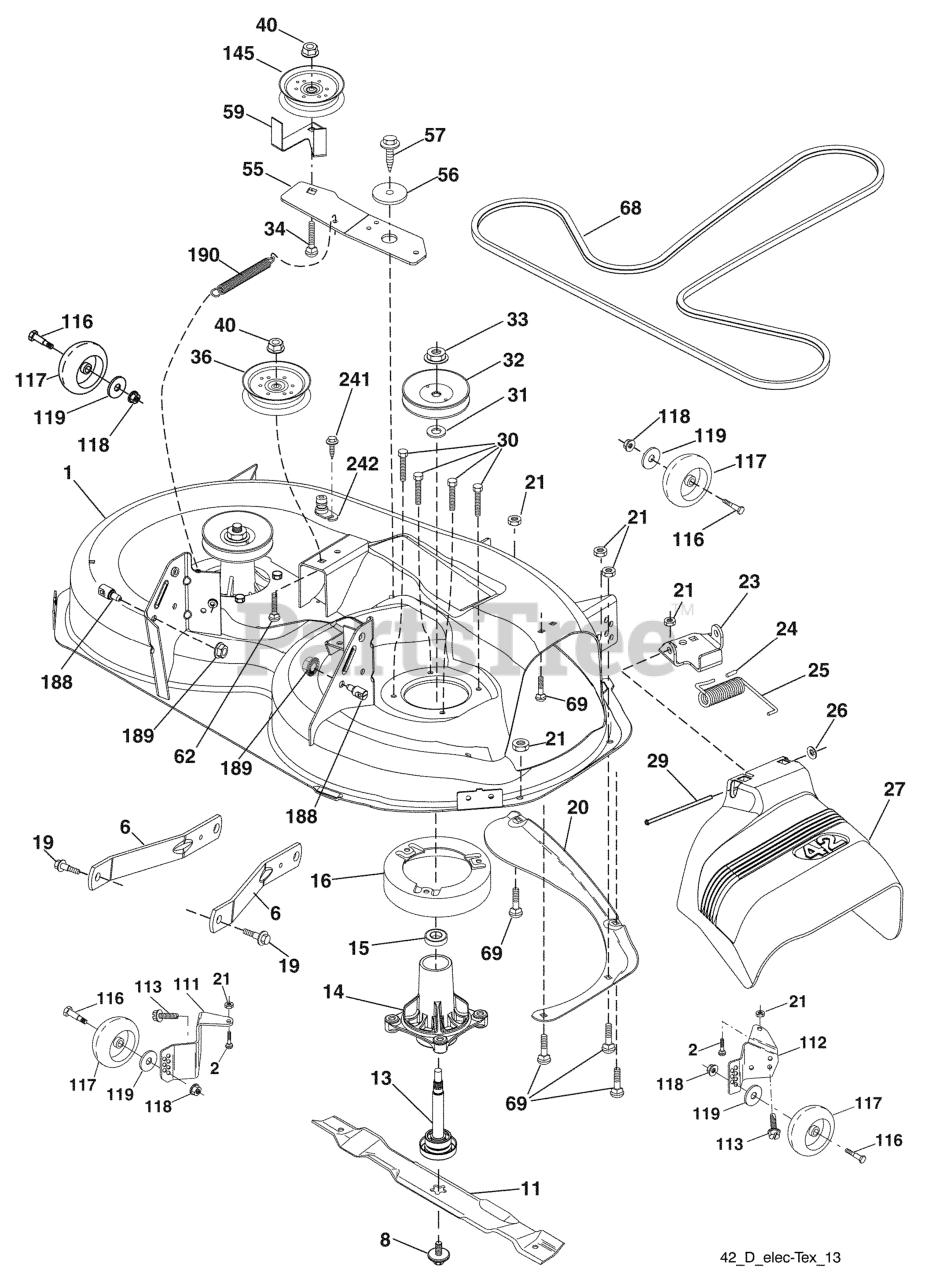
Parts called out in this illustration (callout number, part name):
1	DECK.WELDMENT.42"PAINTD.ORANGE
2	RP BOLT 5/16-18 X3/4 ZN/YEL GR
6	ARM.SUSPENSION.MOWER.R
8	BOLT.WASHER.ASM.7/16-2
11	42" HI-LIFT BLADE
13	SHAFT.ASM.MDRL.N/GREASE.38
14	RP.HOUSING.MANDREL.4PT.
16	STRIPPER.MANDREL.ROUND.BLACK
19	BOLT.SHOULDER
20	BAFFLE.VORTEX
21	LOCKNUT
23	BRKT.DEFLECTOR.38"2005+
24	CAP-SLEEVE LT
25	SPRING.TORSION.DEFLECT
26	NUT PUSH M
27	SHIELD.DEFLECTOR.MOWER.42"BLAC
29	ROD.HINGE
30	SCREW, WASHER HEAD
31	WASHER.SPACER.MANDREL
32	PULLEY/MANDREL
33	NUT.FLANGE.LOCK.TOP
34	BOLT.3/8-16X1.50
36	PULLEY.IDLER.2006
40	NUT LOCK FLG 3/8-16 UNC
55	IDLER.ARM
56	SPACER.RETAINER
57	SCREW 3/8-16X1
59	GUARD, BELT
62	BOLT
68	BELT V SECONDARY
69	BOLT
111	BRKT.WHEEL.GAUGE.LH.42"
112	BRKT.WHEEL.GAUGE.RH.42"
113	BOLT.5/16HEX.WHS.HD
116	BOLT M
117	WHEEL.GAGE.HALF.SPOKED
118	LOCKNUT
119	WASHER.5/16.FLAT.STE.STD.
145	PULLEY.IDLER.48"PRIMARY
188	STUD.FASTNER.W/ANTI-ROTATE
189	NUT LOCK HEX FLANGE 5/16-18
190	SPRING.MOWER.DRIVE.ELECTRIC
241	SCREW.TT.#10-32X.5.3/8.FLANGE
242	PORT.WASHOUT
